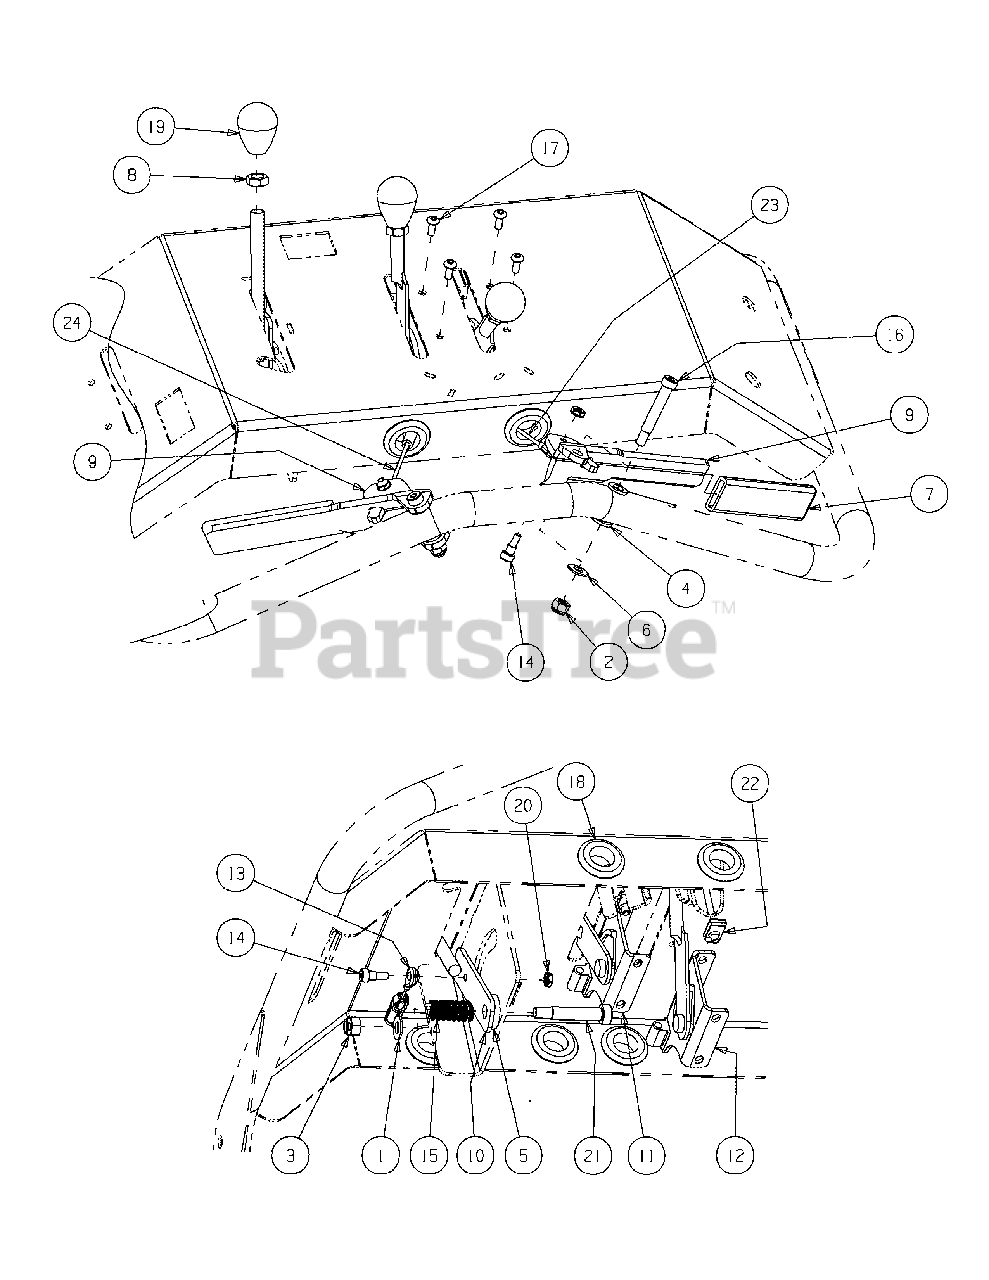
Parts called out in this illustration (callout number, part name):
1	Washer, 5/16
2	Nut, 1/4-20
3	Nut, 5/16-18
4	Washer, 5/16
5	Idler Washer
6	Washer, 1/4 x .630 x .0515
8	Jam Nut, 3/8-16
9	Control Lever Weldment
10	On/Off Lever Weldment
11	3rd Hole Control
12	Remote Deflector Cable
13	On/Off Cable
14	Shoulder Bolt, 1/4 x 1/4
15	Compression Spring
16	Shoulder Bolt, 5/16 x 1.50
17	Hex Cap Screw, 10-24 x .50
18	Rubber Grommet
19	On/Off Lever Knob
20	Nut, 10-24, w/Star Washer
21	Shoulder Bolt 3/8 x 1.50
22	U-Nut, #10-16
23	Control Cable, 74.25
24	Control Cable, 94.25
